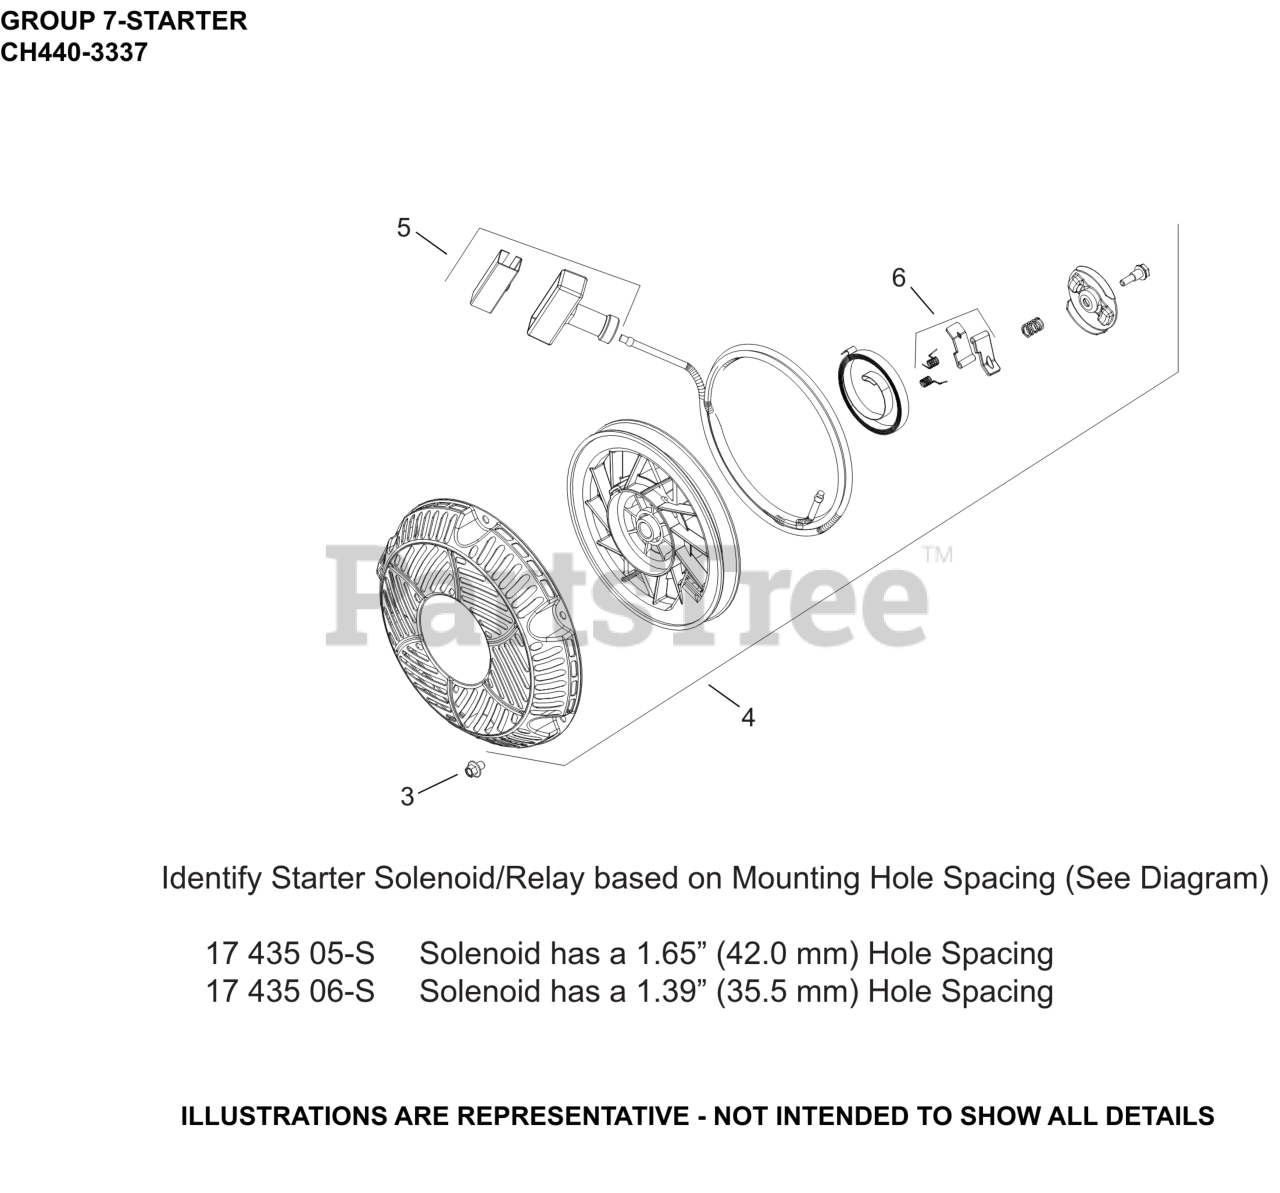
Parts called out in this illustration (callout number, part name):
3	SCREW, M6 X 8 HEX FLANGE HEAD
4	RETRACTABLE STARTER ASSY-(#1716522S)
5	KIT, HANDLE
6	KIT, PAWL REPAIR
